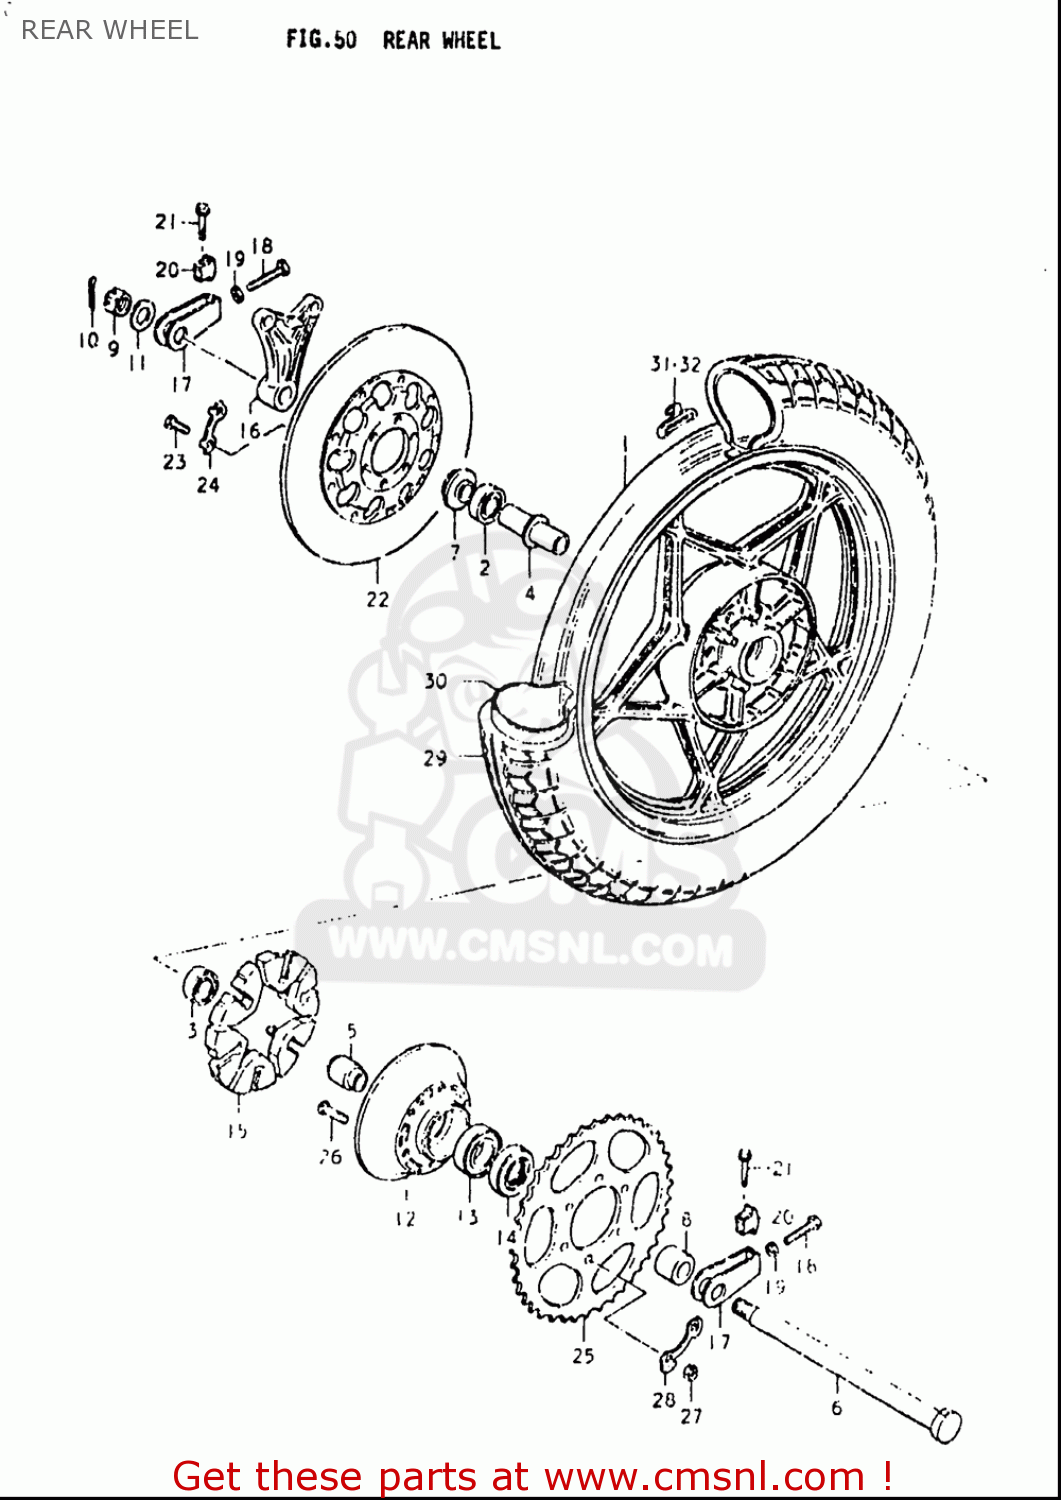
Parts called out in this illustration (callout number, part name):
2	BEARING
3	BEARING
5	RETAINER,REAR SPROCKET D
9	NUT
10	PIN
11	WASHER(17X30X3.2)
12	DRUM,RR SPROCKET MOUNTING
13	BEARING(25X62X17)
14	SEAL,OIL(33X62X7)
15	ABSORBER,RR HUB SHOCK
16	BRACKET,RR,CALIPER
17	ADJUSTER,CHAIN
18	BOLT 8X50
19	NUT
20	SUPPORTER,CHAIN ADJUST
21	BOLT
22	DISC,BRAKE
23	BOLT(8X30)
24	WASHER
25	SPROCKET,RR
26	BOLT(10X35.5)
27	NUT
28	WASHER
30	TUBE,INNER
31	BALANCER,WHEEL
